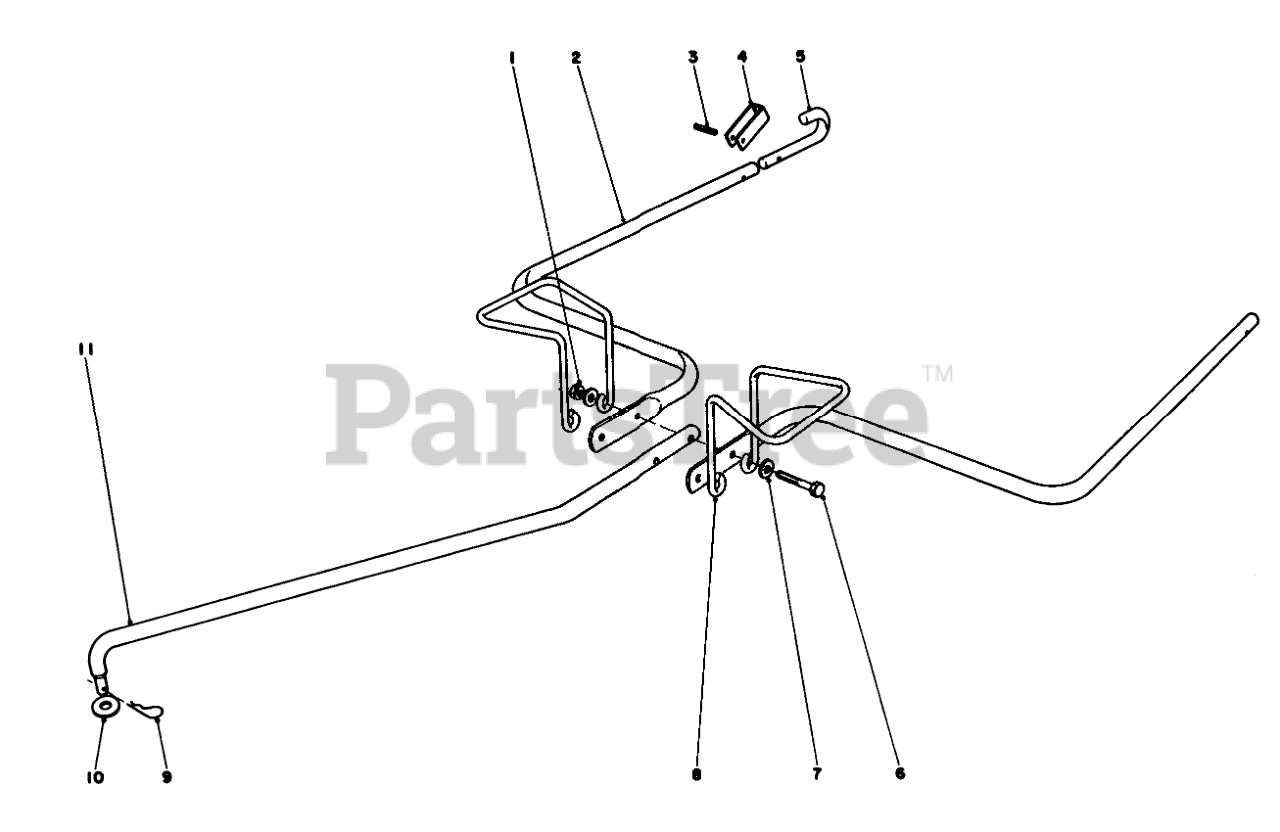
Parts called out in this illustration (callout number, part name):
1	NUT-LOCK, CONE
2	HITCH ARM
3	PIN-ROLL, SLOT
4	HITCH LOCK
5	HOOK HITCH ARM
6	SCREW-HH
7	WASHER-FLAT
8	Support Bag
9	PIN-COTTER
10	PUSH NUT
11	POLE HITCH
